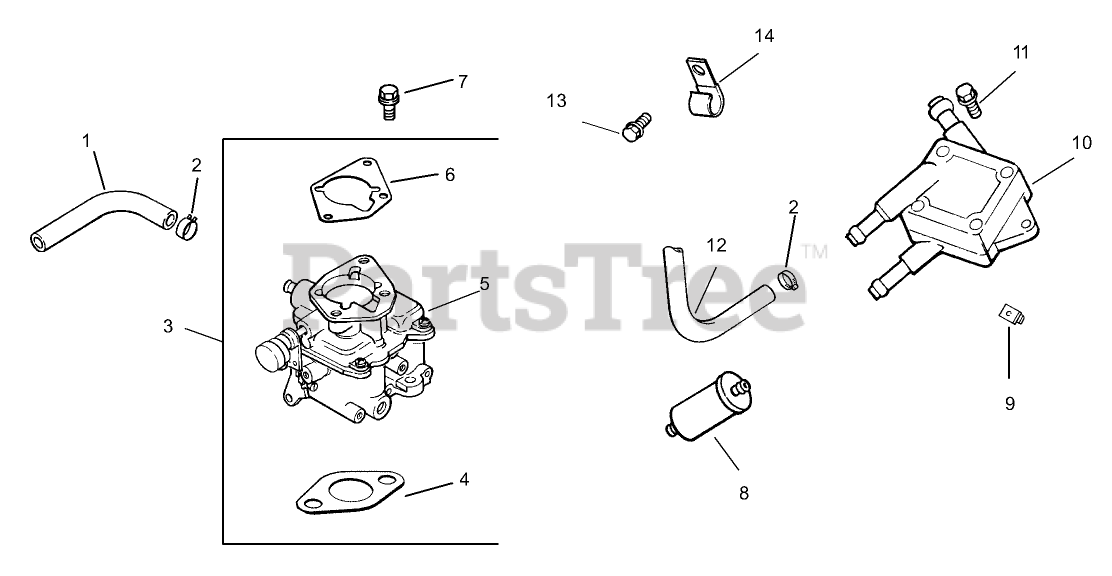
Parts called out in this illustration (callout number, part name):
1	Line-Fuel (9.5)
2	CLAMP-HOSE, SPRING (1/2)
3	Carburetor kit (Includes 4-6)
4	Gasket-Carburetor
5	Carburetor ASM
6	GASKET-BASE, AIR CLEANER
7	SCREW-FLANGE (M6X1.0X30)
8	Filter-Fuel
9	Nut-Plastic
10	PUMP-FUEL
11	SCREW-TAP (M6X1.7X18)
12	Line-Fuel, Flexible (15.5)
13	Screw-HF (M6x1.0x12)
14	CLIP-CABLE
